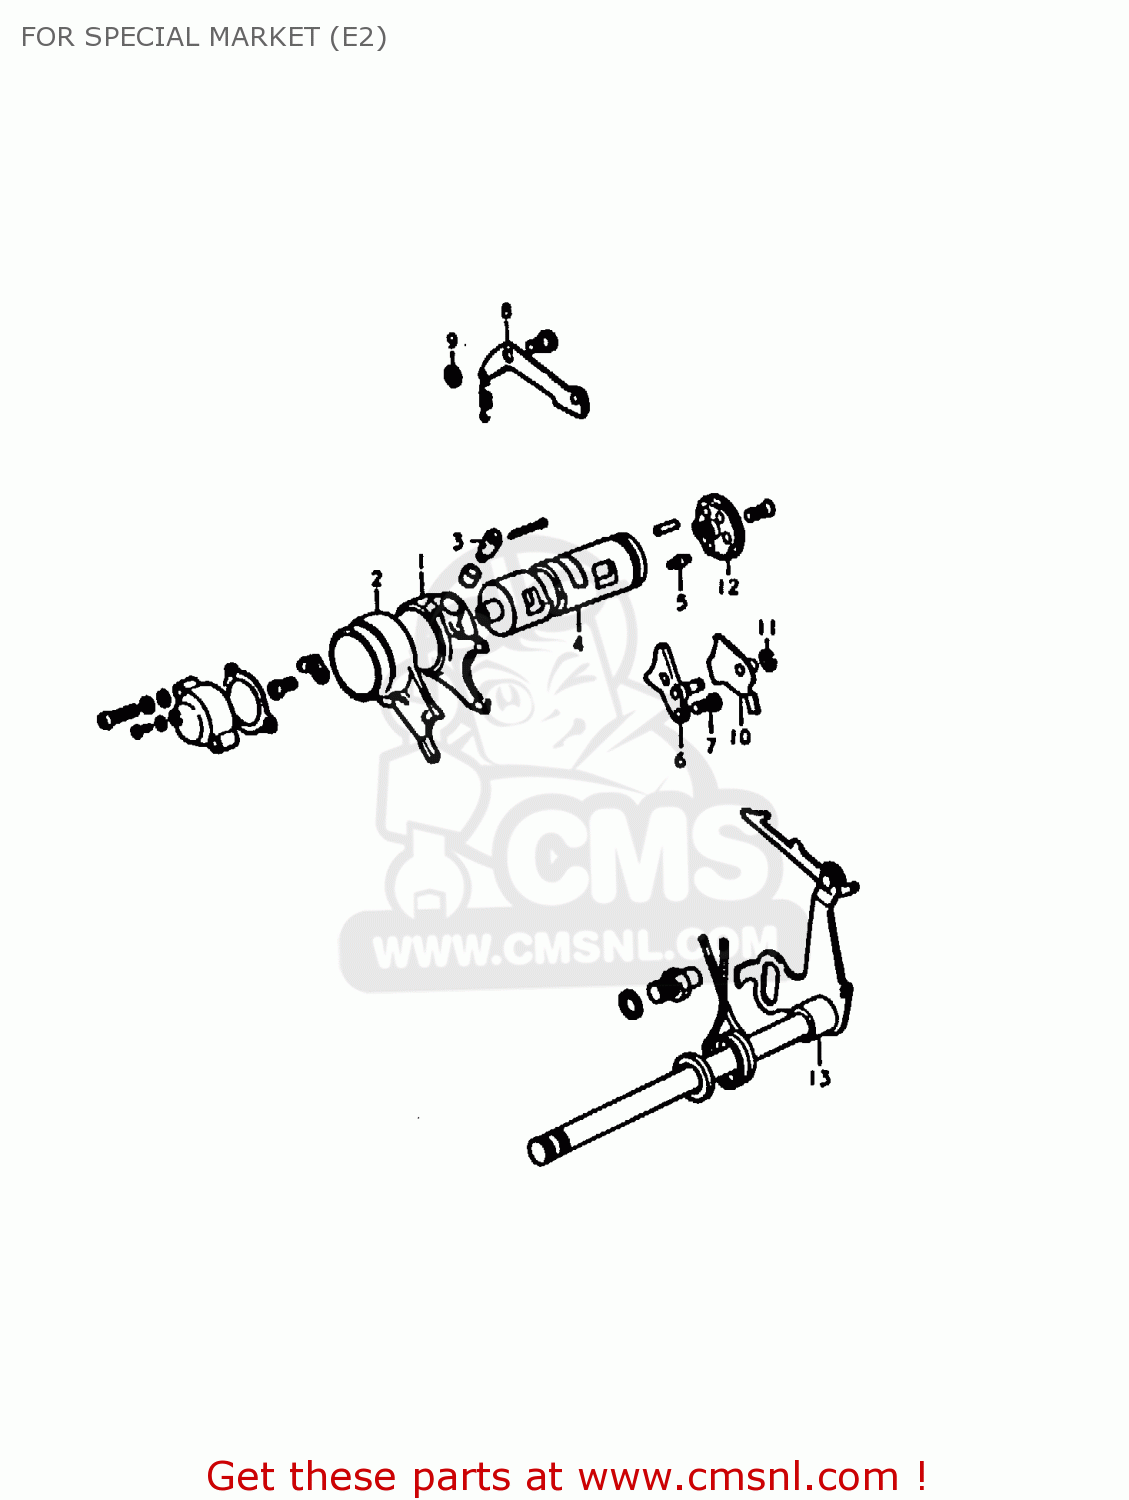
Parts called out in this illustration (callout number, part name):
1	HEAD,CYLINDER
2	GASKET,CYLINDER HEAD (NAS)
5	GASKET,CYLINDER (MCA)
6	BOLT,STUD
7	NUT (8MM)
8	LOCK WASHER
9	SPARK PLUG
31	BOLT 8X110
33	WASHER
34	WASHER
35	LOCK WASHER
36	WASHER,LOCK,8.
37	NUT
